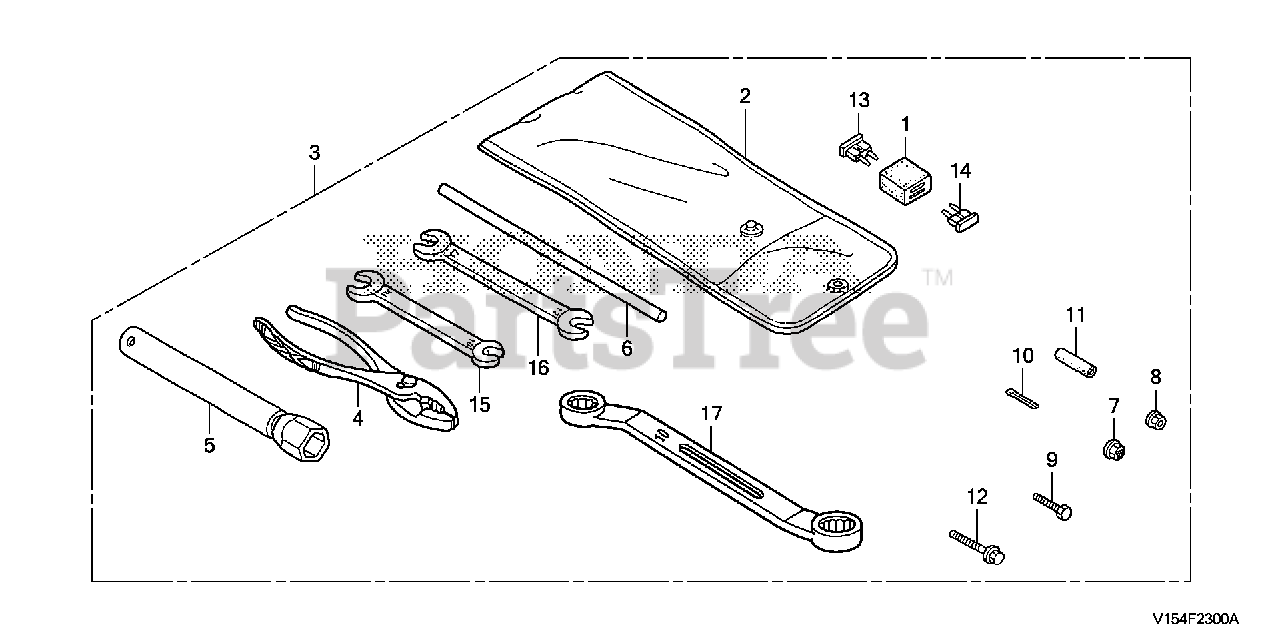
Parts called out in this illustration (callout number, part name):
1	SUSPENSION, TURN SIGNAL RELAY (MITSUBA)
2	BAG, TOOL
4	PLIERS (135) (RIKEN)
5	WRENCH, SPARK PLUG
6	HANDLE, BOX WRENCH
7	NUT, SELF-LOCK (8MM) (CLINCH)
9	BOLT, HEX. (8X25)
10	PIN, SPLIT (2.5X30)
11	BULK HOSE, VACUUM (17X1000) (17X27)
12	BOLT, FLANGE (8X25)
13	FUSE, MINI (5A)
14	FUSE, MINI (15A)
15	SPANNER (10X14)
16	SPANNER (12X17)
17	WRENCH, EYE (10X12)
